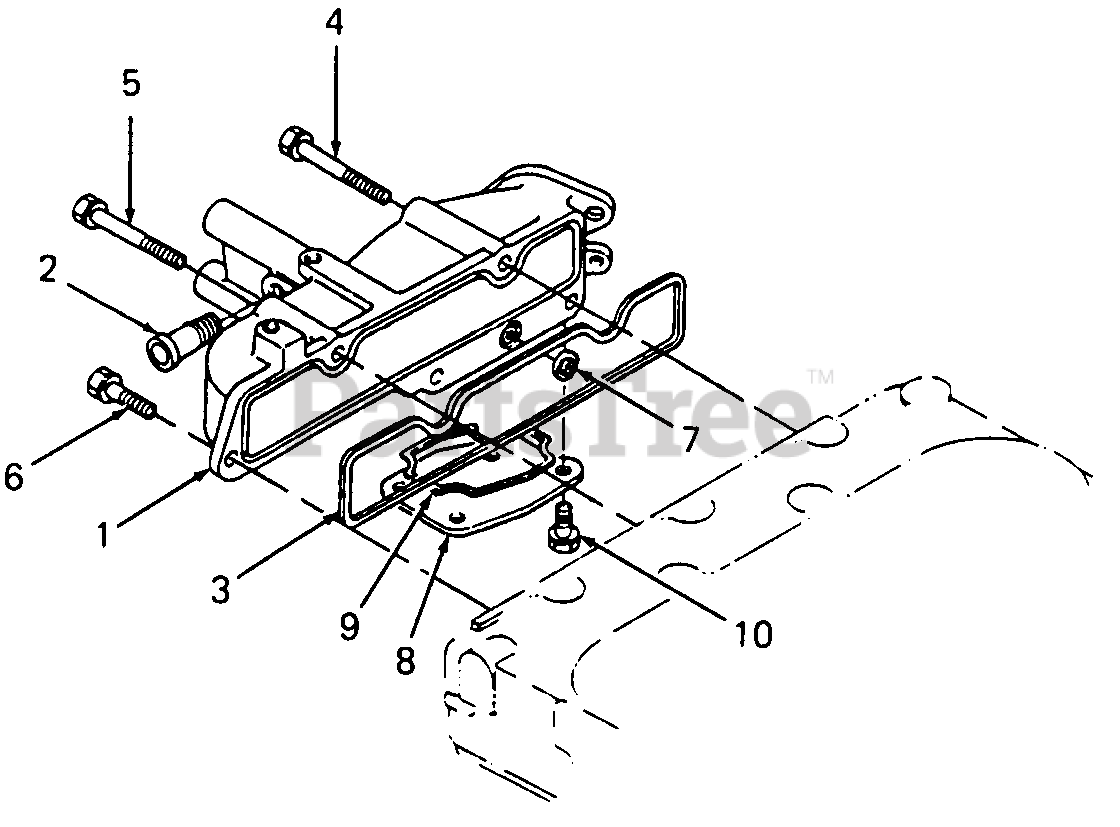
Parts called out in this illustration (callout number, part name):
1	Manifold, Inlet
2	Pipe, Water, Return #1
3	Gasket, Inlet Manifold
